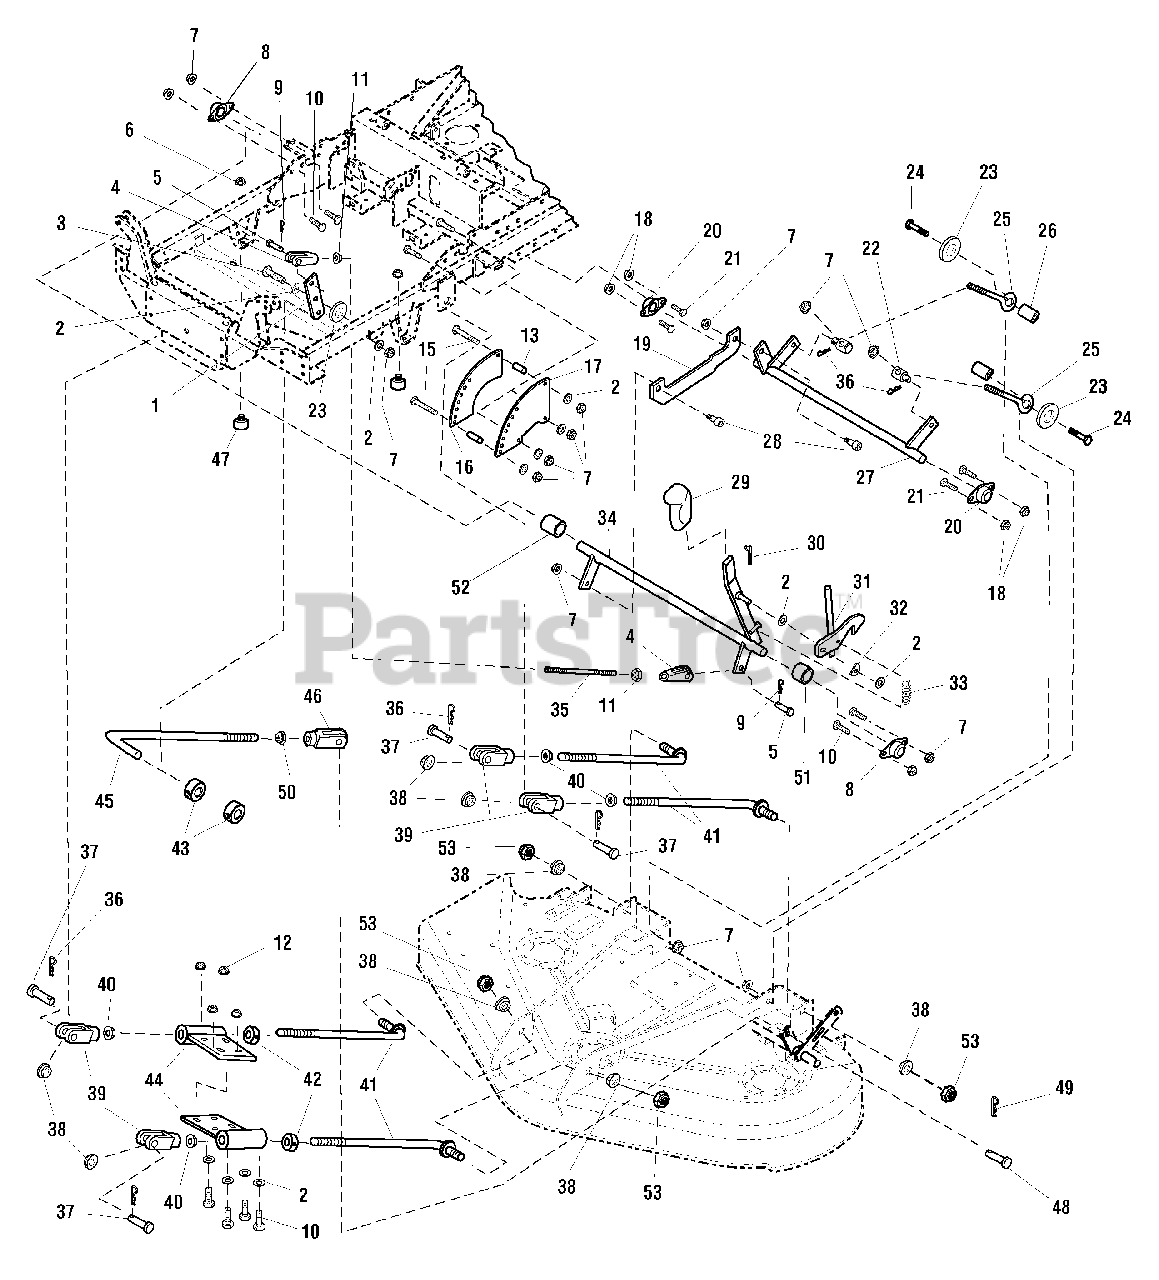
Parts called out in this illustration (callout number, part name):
1	LINK, Reversing
2	WASHER, 3/8, SAE
3	CAPSCREW, Hex Head, 3/8-16 X 1-1/2
4	CLEVIS, Plastic, 3/8-24
5	PIN, 3/8 DIA X 1"
6	NUT, Hex Serrated Flange, 1/4-20
7	NUT, Hex Nylon Lock, 3/8-16
8	BEARING, Bronze Flange3/4"
9	PIN, Cotter
10	CAPSCREW, Hex Head, 3/8-16 X 3/4
11	JAM NUT, Hex, 3/8-24
12	NUT, Hex Serrated Flange, 3/8-16
15	CAPSCREW, Hex Head, 3/8-16 X 2-1/2
16	DECK HEIGHT PLATE, Inner, Orange
16	DECK HEIGHT PLATE, Inner, Red
17	DECK HEIGHT PLATE, Outer, Orange
17	DECK HEIGHT PLATE, Outer, Red
18	NUT, Hex Nylon Lock, 5/16-18
19	LINK, Deck Lift, Red
19	LINK, Deck Lift, Orange
20	BUSHING, Bronze Flange
21	CAPSCREW, Hex Head, 5/16-18 X 3/4
22	ADJUSTER, Brake Linkage
23	WASHER, 1-3/4 OD X .390 ID
24	CAPSCREW, Hex Head, 3/8-16 X 1-3/4
25	EYE BOLT, 3/8-16 X 6, 3.0 THRD, 1 EYE
27	LIFT SHAFT, Rear Deck, Orange
27	LIFT SHAFT, Rear Deck, Red
28	BOLT, 1/2" X 3/8" Shoulder
29	HANDLE COVER
30	PIN, Cotter, 3/16 X 1-1/2
31	DECK LOCK, Orange
31	DECK LOCK, Red
32	WASHER, Spring, 3/8
33	SPRING, Extension
34	SHAFT, Deck Height, Orange
34	SHAFT, Deck Height, Red
36	HAIRPIN
37	PIN, Clevis, 1/2 X 1-1/2
38	BUSHING, Support
39	CLEVIS, 1/2-20
40	NUT, Hex Jam, 1/2-20
41	ROD, Deck Hanger
42	SPLIT COLLAR, 1/2"
43	SPLIT COLLAR, 1/2"
44	DECK STABILIZER, Orange
44	DECK STABILIZER, Red
45	CONNECTING ROD, Roller (44" DECK)
45	CONNECTING ROD, Roller (50" DECK)
46	CLEVIS, 1/2-20
47	BUMPER, Rubber, 1/4-20
48	PIN, Clevis, 1/2 X 1-1/2
49	HAIRPIN
50	NUT, Hex Jam, 1/2-20
51	SPACER, .76 X 1.00 X .50
52	SPACER, .76 X 1.00 X 1.00
53	NUT, Hex Nylon Lock, 1/2-20
